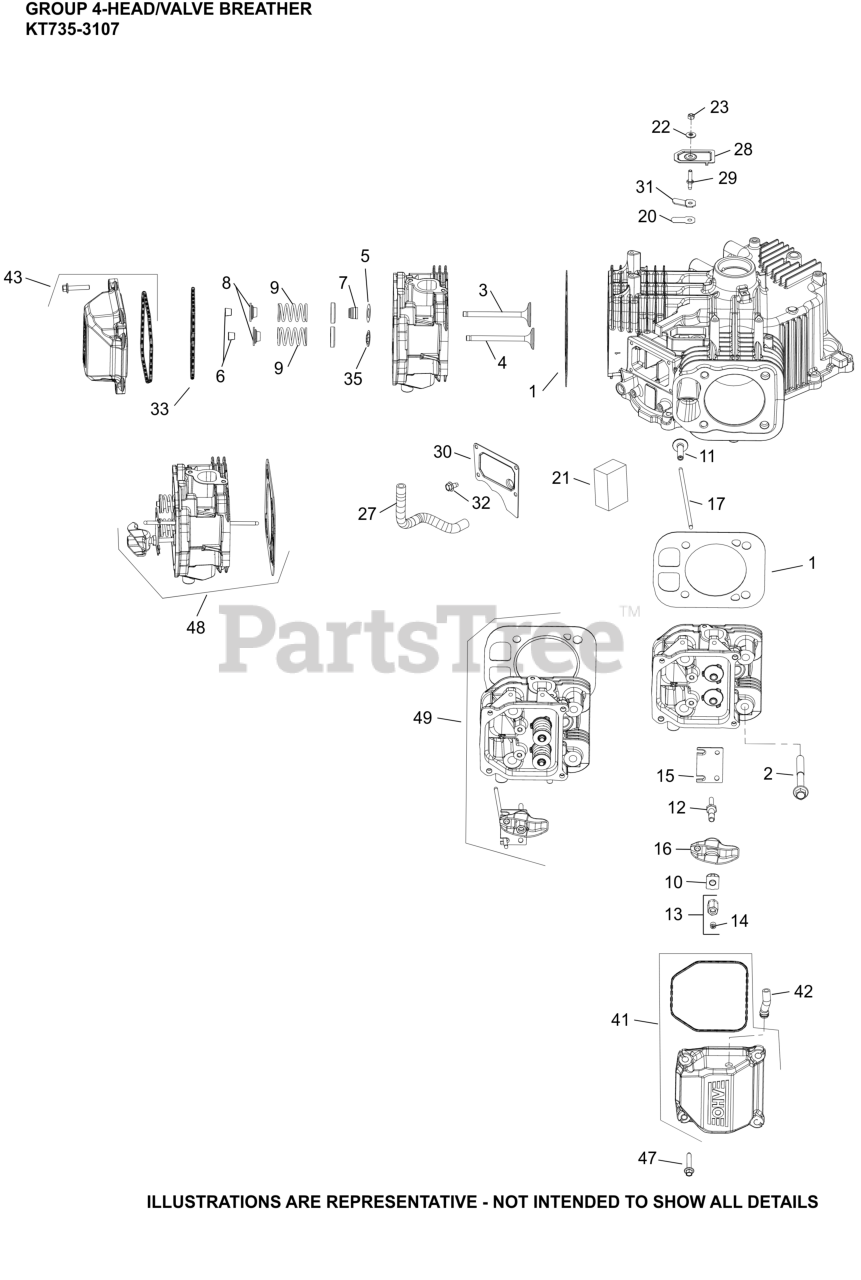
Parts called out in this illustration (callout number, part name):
1	KIT, CYLINDER HEAD GASKET
2	SCREW, HEX FLANGE M10 X 1.5-6g X 90mm
3	VALVE, INTAKE
3	VALVE, INTAKE (.25) - (#2401702S)
4	VALVE, EXHAUST
4	VALVE, EXHAUST (.25)
5	SPACER (.010")
6	KIT, RETAINER
7	SEAL, VALVE BAND
8	CAP, VALVE SPRING
9	SPRING VALVE
10	PIVOT, ROCKER ARM
12	STUD, ROCKER
13	HEX NUT ASSEMBLY
14	SCREW, SET
15	PLATE, GUIDE
16	ARM, ROCKER
17	ROD, PUSH
20	REED, BREATHER
21	FILTER, BREATHER
22	WASHER, SEALING
23	NUT, LOCK M5X.8
27	HOSE, BREATHER
28	COVER, BREATHER REED
30	COVER, BREATHER MEDIA
31	RETAINER, REED
32	SCREW, THREAD FORMING
33	O-RING (YELLOW), VALVE CO
35	RETAINER, VALVE GUIDE (KM)
41	KIT,BREATHER VALVE COVER (PLASTIC)
42	HOSE, FP-USE 32 326 07-S(PLASTIC COVERS)
43	KIT, VALVE COVER-PLAIN (PLASTIC)
47	SCREW, HEX FLANGE (M6 X 31.625 DOG PT)
48	KIT, #1 CYLINDER HEAD
49	KIT, #2 CYLINDER HEAD
